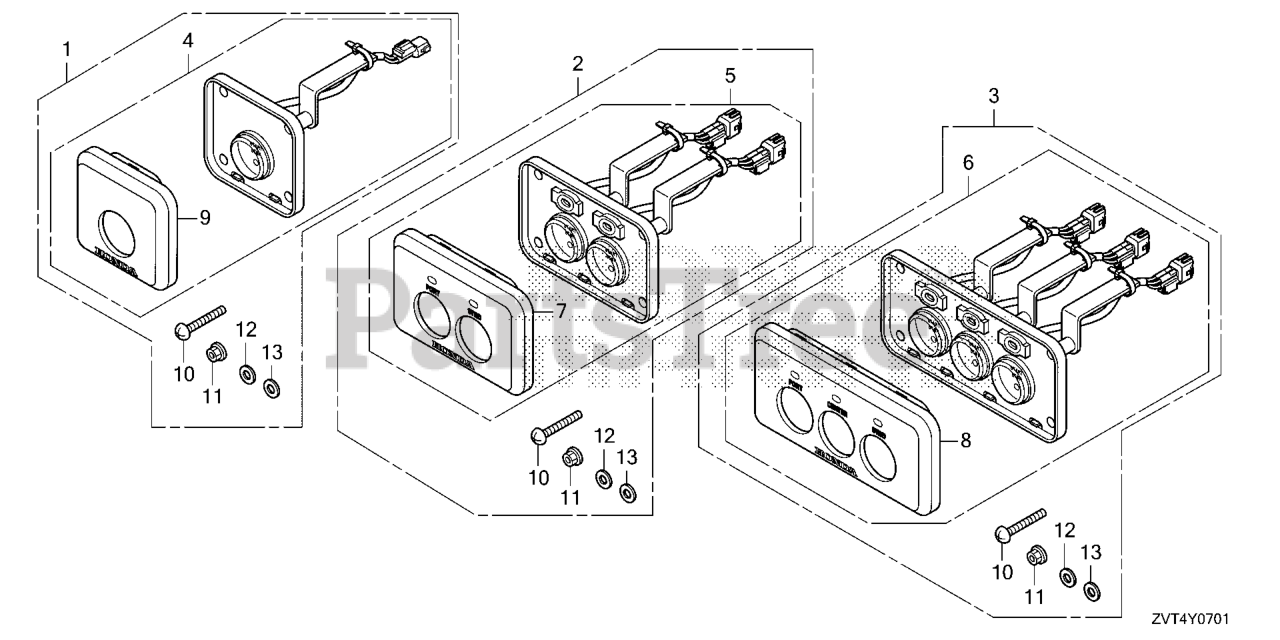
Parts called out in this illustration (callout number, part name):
1	PANEL KIT, START STOP SWITCH (ALL)
1	PANEL KIT, S/S SW
2	PANEL KIT, S/S SW
3	PANEL KIT, S/S SW
4	PANEL ASSY., START STOP (ALL)
4	PANEL ASSY., START STOP (SINGLE)
5	PANEL ASSY., START STOP (TWIN)
6	PANEL ASSY., START STOP (TRIPLE)
7	PANEL, START STOP (TWIN)
8	PANEL, START STOP (TRIPLE)
9	PANEL, START STOP (ALL)
9	PANEL, START STOP (SINGLE)
10	SCREW, PAN (5X40) DUAL QTY = (8) (SINGLE)
11	NUT, FLANGE (5MM)
12	WASHER, PLAIN (5MM)
13	WASHER, SPG (5MM)
